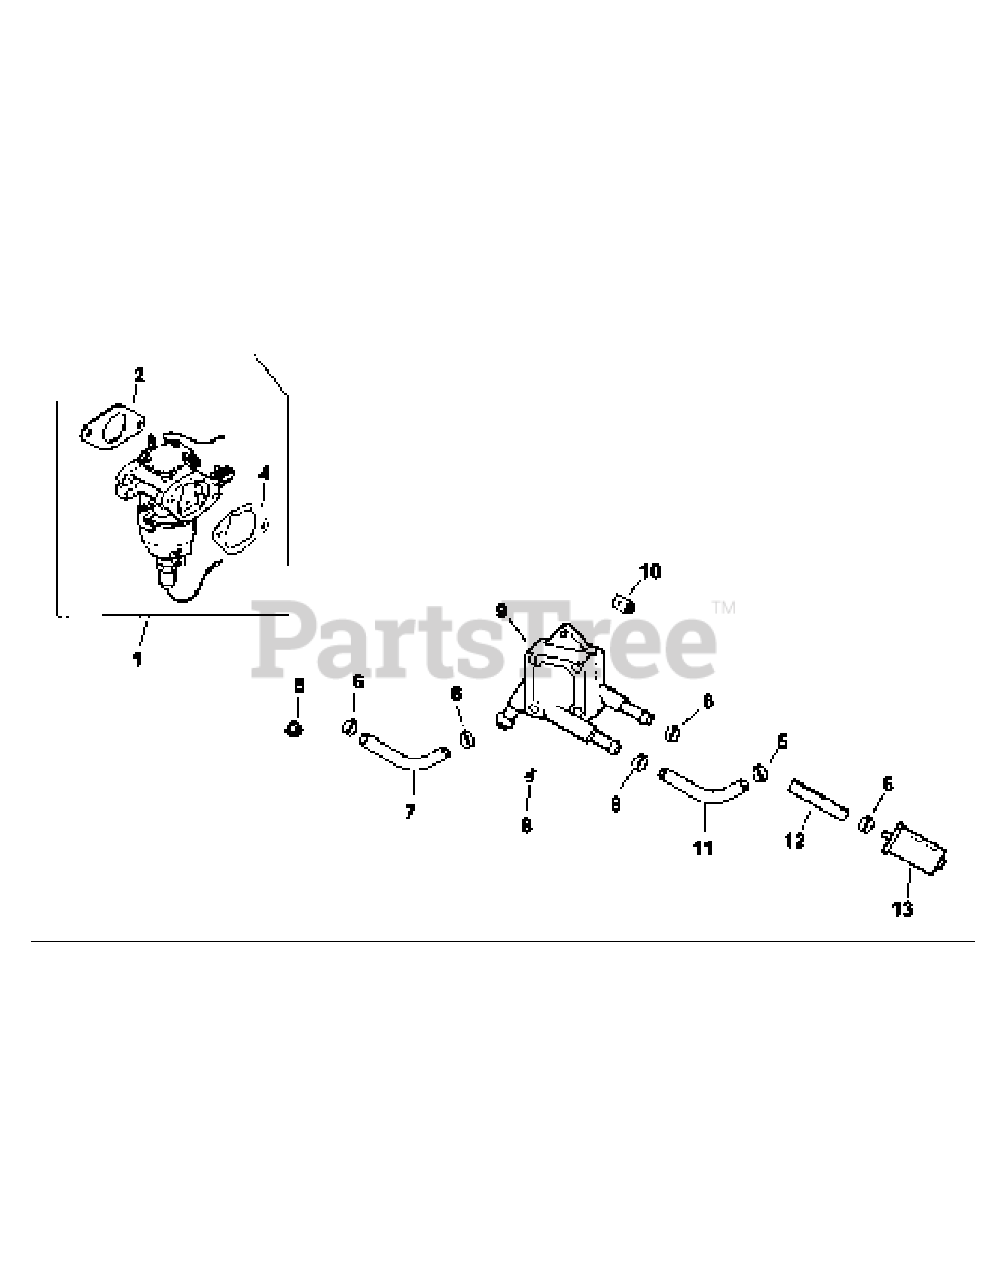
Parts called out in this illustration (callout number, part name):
1	Kit, Carburetor w/Gasket
2	Gasket, Carburetor
4	Gasket, Air Cleaner Ell
5	Nut, Hex Flange M6x1.0
7	Line, Fuel 12-1/4"
8	Screw, Hex Cap M6x1.7x18
9	Pump, Fuel-Pulse
11	Line, Fuel 10.5"
12	Line, Fuel 3-1/2"
